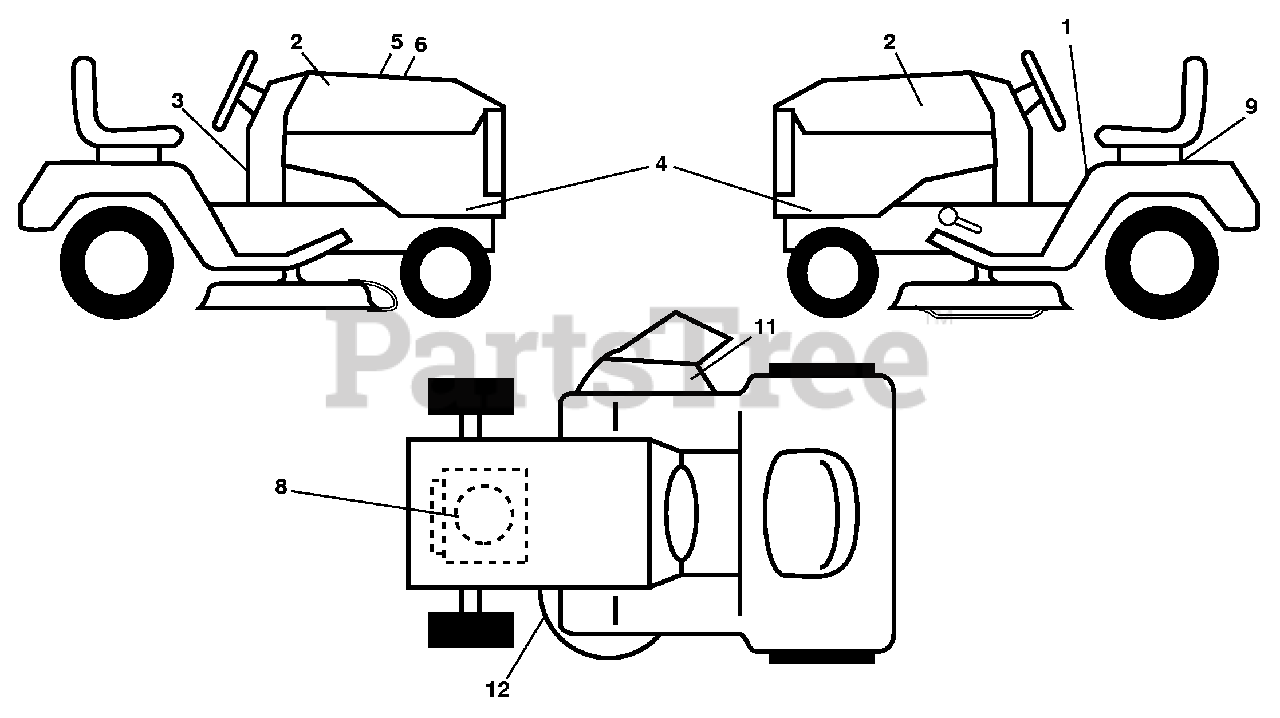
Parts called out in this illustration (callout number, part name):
1	Decal, Fender Warn./Instructions
2	Decal, Hood Logo
3	Decal, Warning Spark Arrestor
4	Decal, Hood Panel
5	Decal, Customer Respons.
6	Decal, Replacement
8	Decal, Engine
9	Decal, Battery Dnge/Poi
11	Decal, Warning
12	Decal, Mower V-Belt Schematic
